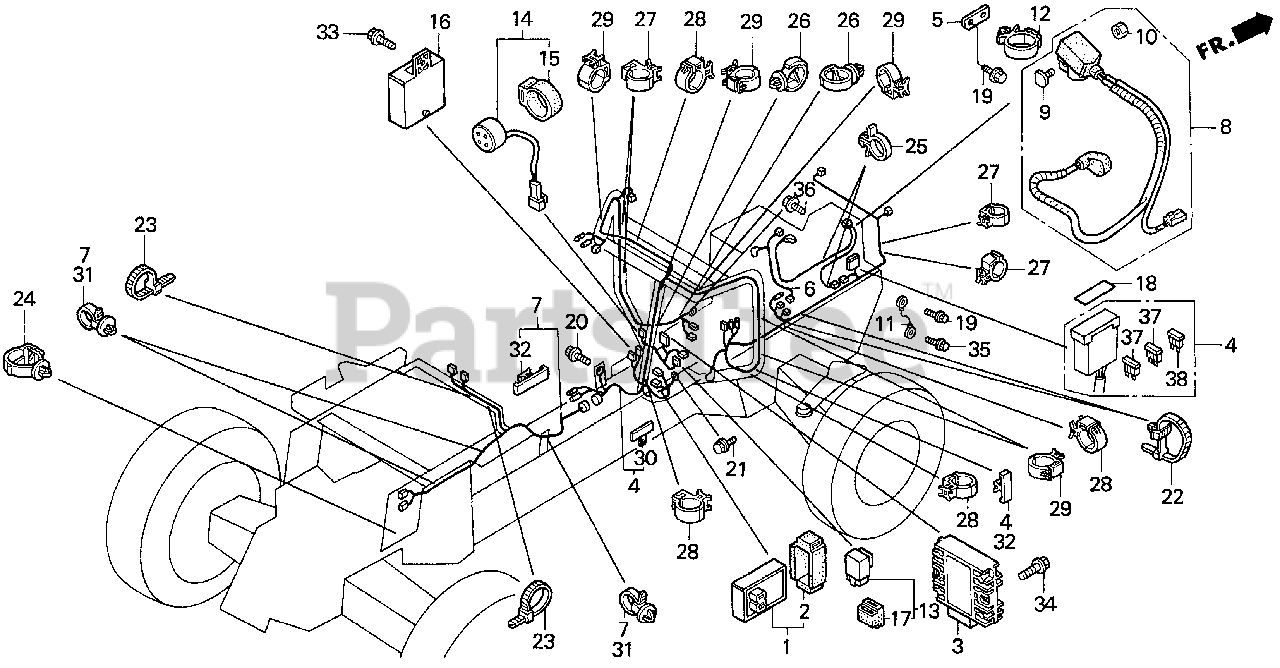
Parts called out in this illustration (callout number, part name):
1	MODULE, IGNITION CONTROL (CDI)
2	CUSHION, IGNITION CONTROL MODULE
3	RECTIFIER, REGULATOR
4	WIRE HARNESS ASSY., MAIN
5	BRACKET, WIRE HARNESS CLIP
6	WIRE HARNESS ASSY., ENGINE
7	WIRE HARNESS ASSY., RR.
8	CABLE ASSY., STARTER
9	BOLT, BATTERY TERMINAL
10	NUT, BATTERY TERMINAL
11	CABLE, SUB-GROUND
12	CLAMP, ENGINE SUB-WIRE
13	RELAY ASSY., CONTROL (20A)
14	BUZZER ASSY., WARNING
15	SUSPENSION, AUDIBLE PILOT
16	RELAY ASSY., COMBINATION
17	SUSPENSION, STARTER RELAY (TATEISHI)
18	LABEL, FUSE (ENGLISH)
19	BOLT, FLANGE (6X14)
20	BOLT, GROUND (6X16) (SN)
21	BOLT, GROUND (6X12) (SN)
22	BAND, WIRE HARNESS (WHITE)
23	BAND, CABLE (120MM) (BLACK)
24	CLIP, WIRE HARNESS
25	CLIP, WIRE HARNESS
26	CLIP, WIRE HARNESS (25MM)
27	CLIP, CABLE (10MM)
28	CLIP, CABLE (15MM)
29	CLIP, CABLE (20MM)
30	CLIP, WIRE HARNESS
31	BAND, WIRE HARNESS (110MM) (BROWN)
32	CLIP, WIRE HARNESS (BLACK)
33	BOLT, FLANGE (6X14)
34	BOLT, FLANGE (6X22)
35	BOLT, FLANGE (8X12)
36	BOLT, FLANGE (8X16)
37	FUSE, BLADE (5A)
38	FUSE, BLADE (20A)
